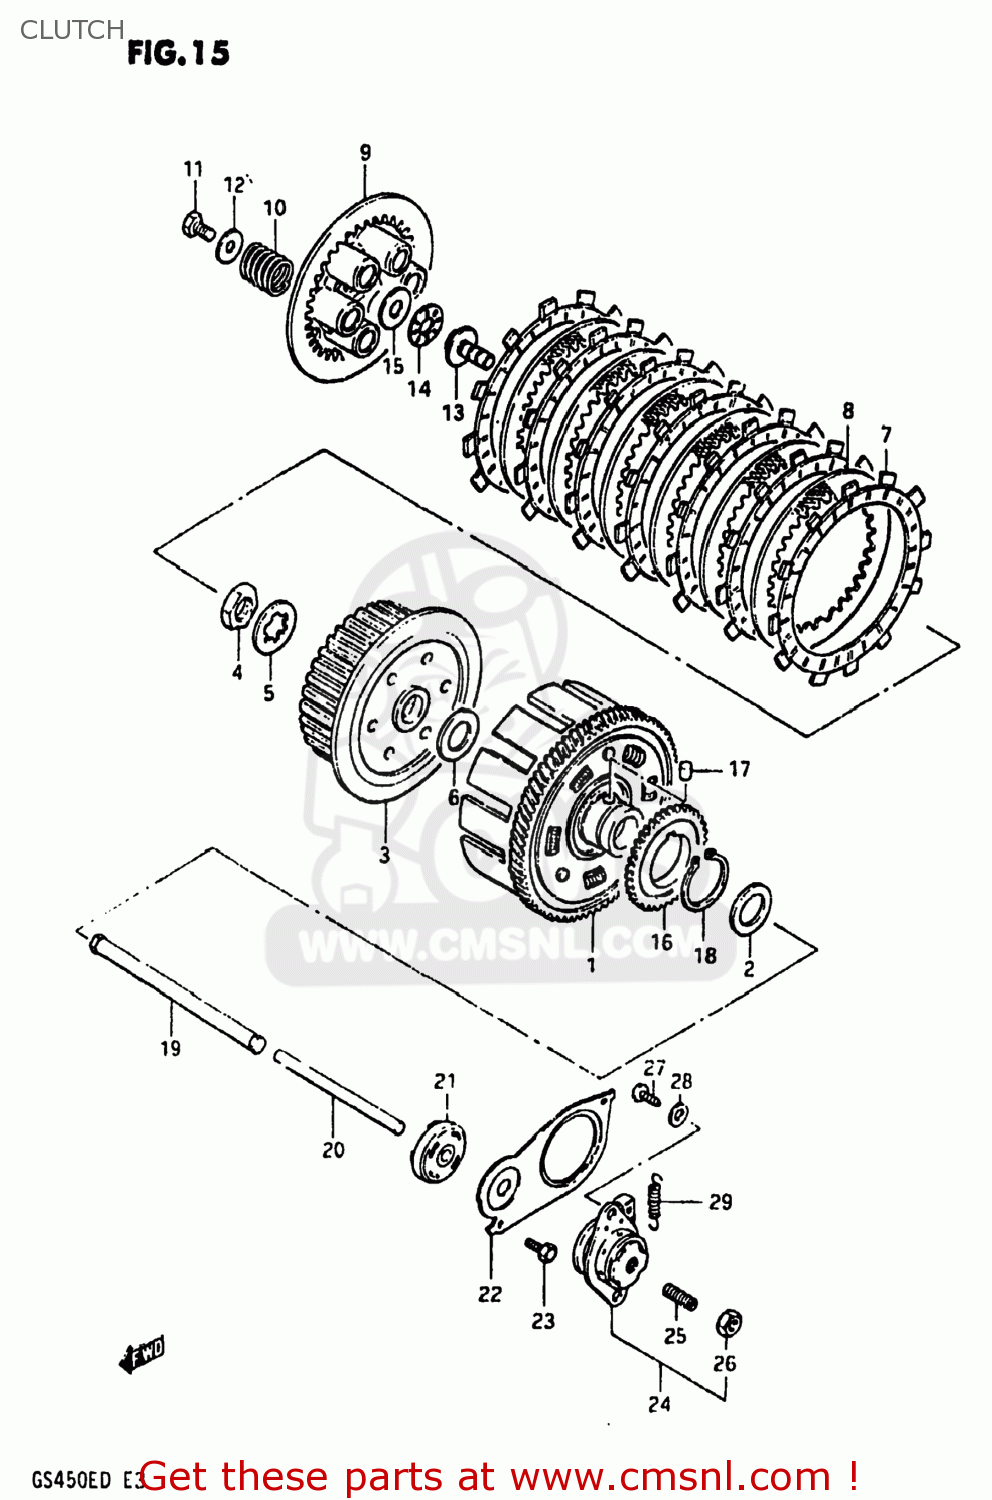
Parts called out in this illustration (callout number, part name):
1	GEAR ASSEMBLY,PRIMARY DRIVE
2	WASHER
3	HUB,CLUTCH SLEEVE
4	NUT (20MM)
5	WASHER,LOCK
6	WASHER(20X44X3)
7	PLATE,CLUTCH DRIVE (MCA)
8	PLATE,CLUTCH DRIVEN (NAS)
9	DISC,CLUTCH PRESSURE
10	SPRING
11	BOLT, UPPER
12	WASHER
13	PIECE,CLUTCH PUSH
14	BEARING(15X28X2)
15	WASHER
16	GEAR,OIL PUMP DRIVE
17	PIN(6X6)
18	CIRCLIP
19	ROD,CLUTCH PUSH
20	ROD,CLUTCH PUSH
21	SEAL,OIL(6X34X10)
22	PLATE,CLUTCH PUSH ROD
23	BOLT
24	SCREW ASSY,CLUTCH RELEASE
25	SCREW
26	NUT 6MM
27	SCREW
28	WASHER
29	SPRING
